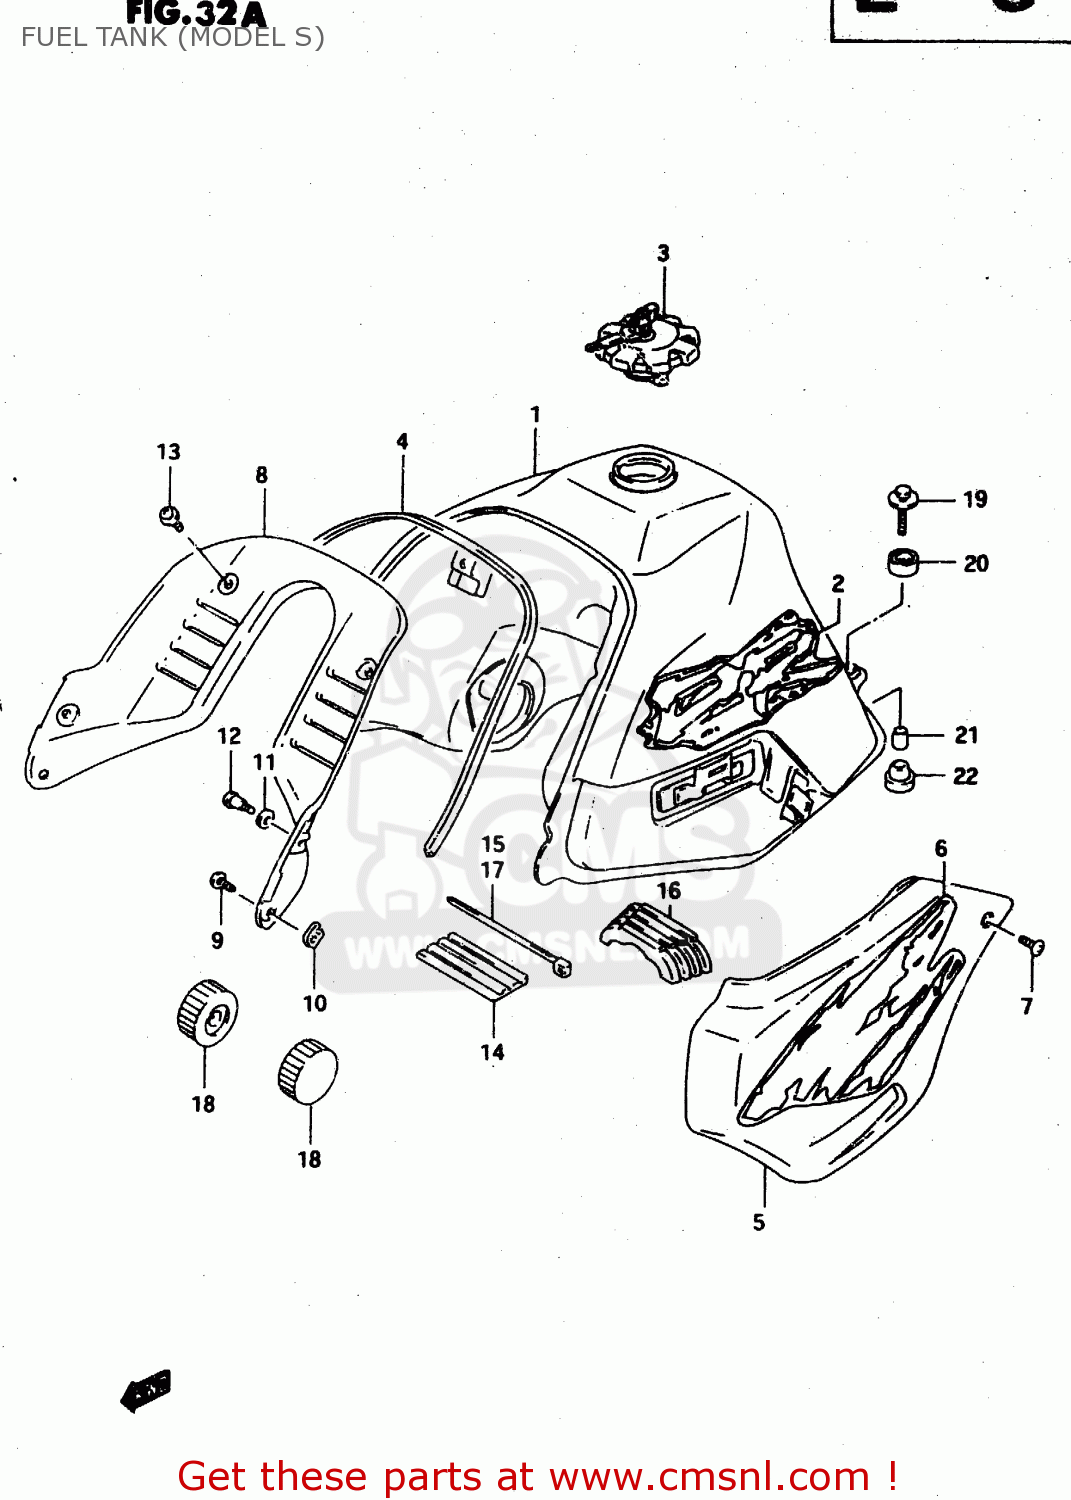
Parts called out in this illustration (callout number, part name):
1	TANK ASSEMBLY,FUEL
2	EMBLEM SET,FUEL TANK
3	CAP SET,FUEL TANK
4	MOLD,COWLING
5	COVER,FUEL TANK,R
6	TAPE,TANK COVER,L
7	SCREW
8	COVER,FUEL TANK,FRONT
9	SCREW
10	NUT
11	WASHER (5.1X20X1.4)
12	SCREW(5X18)
13	SCREW
14	CUSHION,FUEL TANK UPR FR
15	CLAMP
16	CUSHION,TANK UPR RR
17	CLAMP(L:300)
18	CUSHION,FUEL TANK FR
19	BOLT
20	CUSHION
21	SPACER
22	CUSHION
